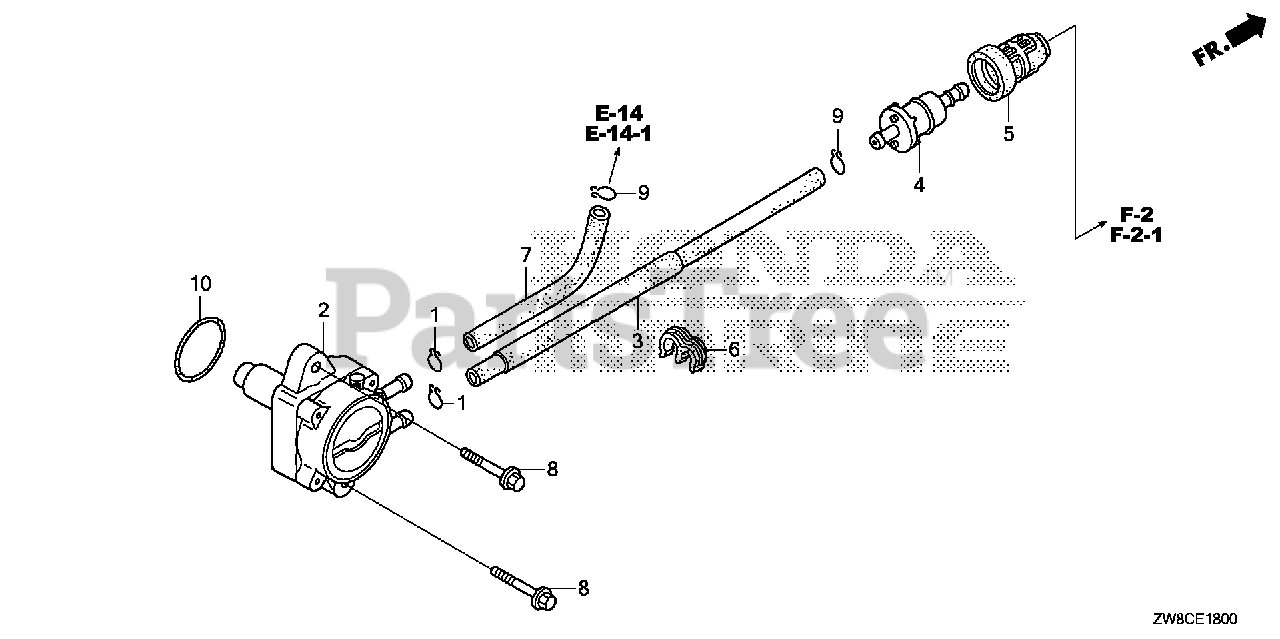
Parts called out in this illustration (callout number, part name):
1	CLIP, TUBE (ENGINE NO.)
2	PUMP ASSY., FUEL (MSDS)
3	TUBE B, FUEL
4	FILTER, FUEL
5	SUSPENSION, STRAINER
6	CLAMP, TUBE (7.5-11.5) (BLACK)
7	TUBE, FUEL
8	BOLT, FLANGE (6X22)
9	CLIP, TUBE (B10)
10	O-RING (31.2X2.4)
